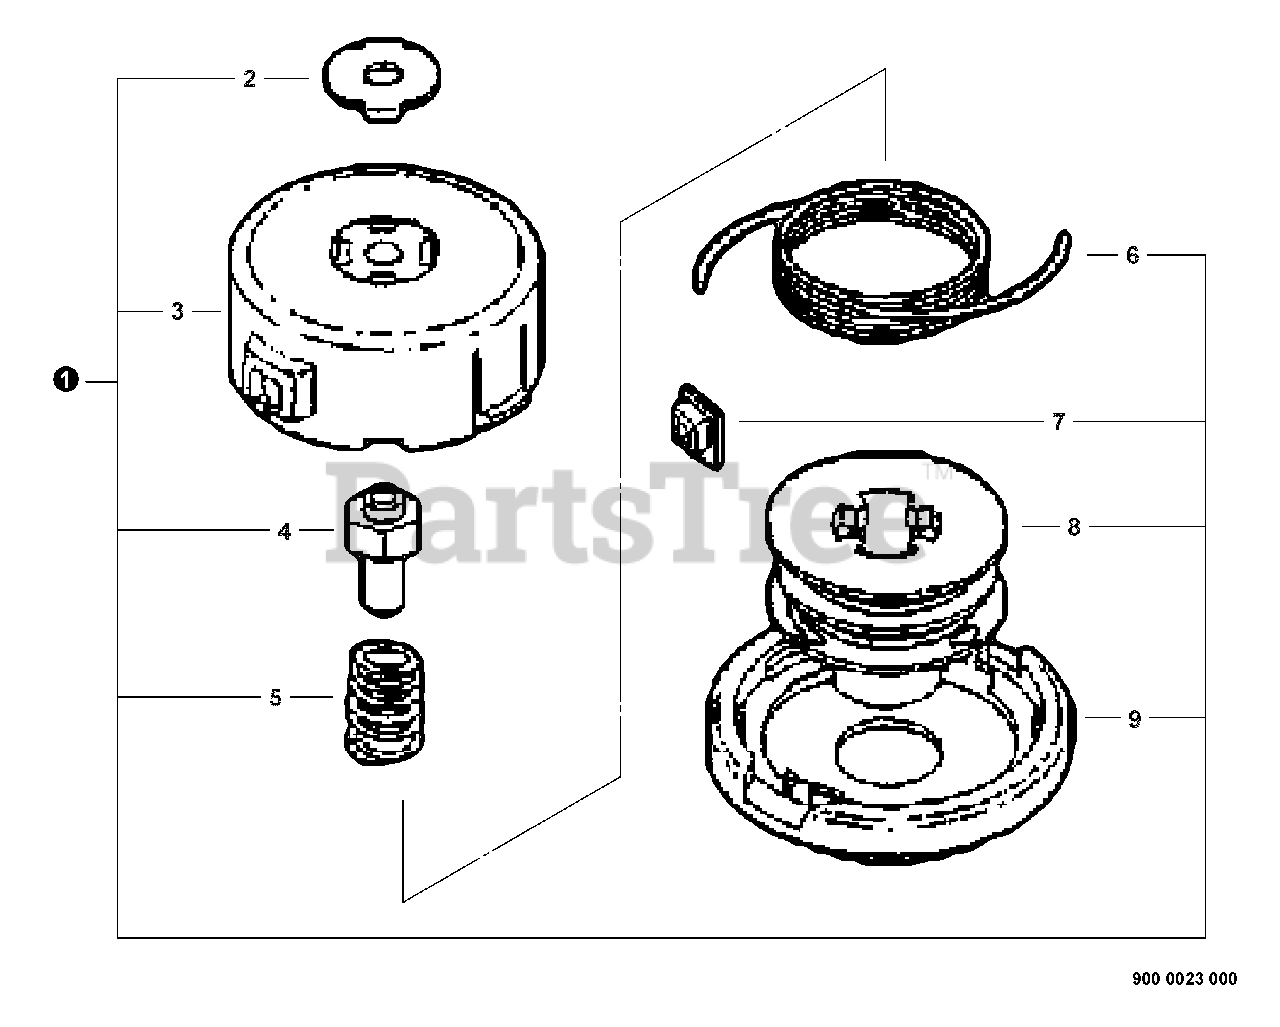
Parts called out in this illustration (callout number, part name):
1	HEAD, B4-R TAP & GO TRIMMER
2	PLATE, TOP
3	COVER, SPOOL
4	BUSHING
6	LINE, NYLON TRIMMER
9	HOUSING, SPOOL
